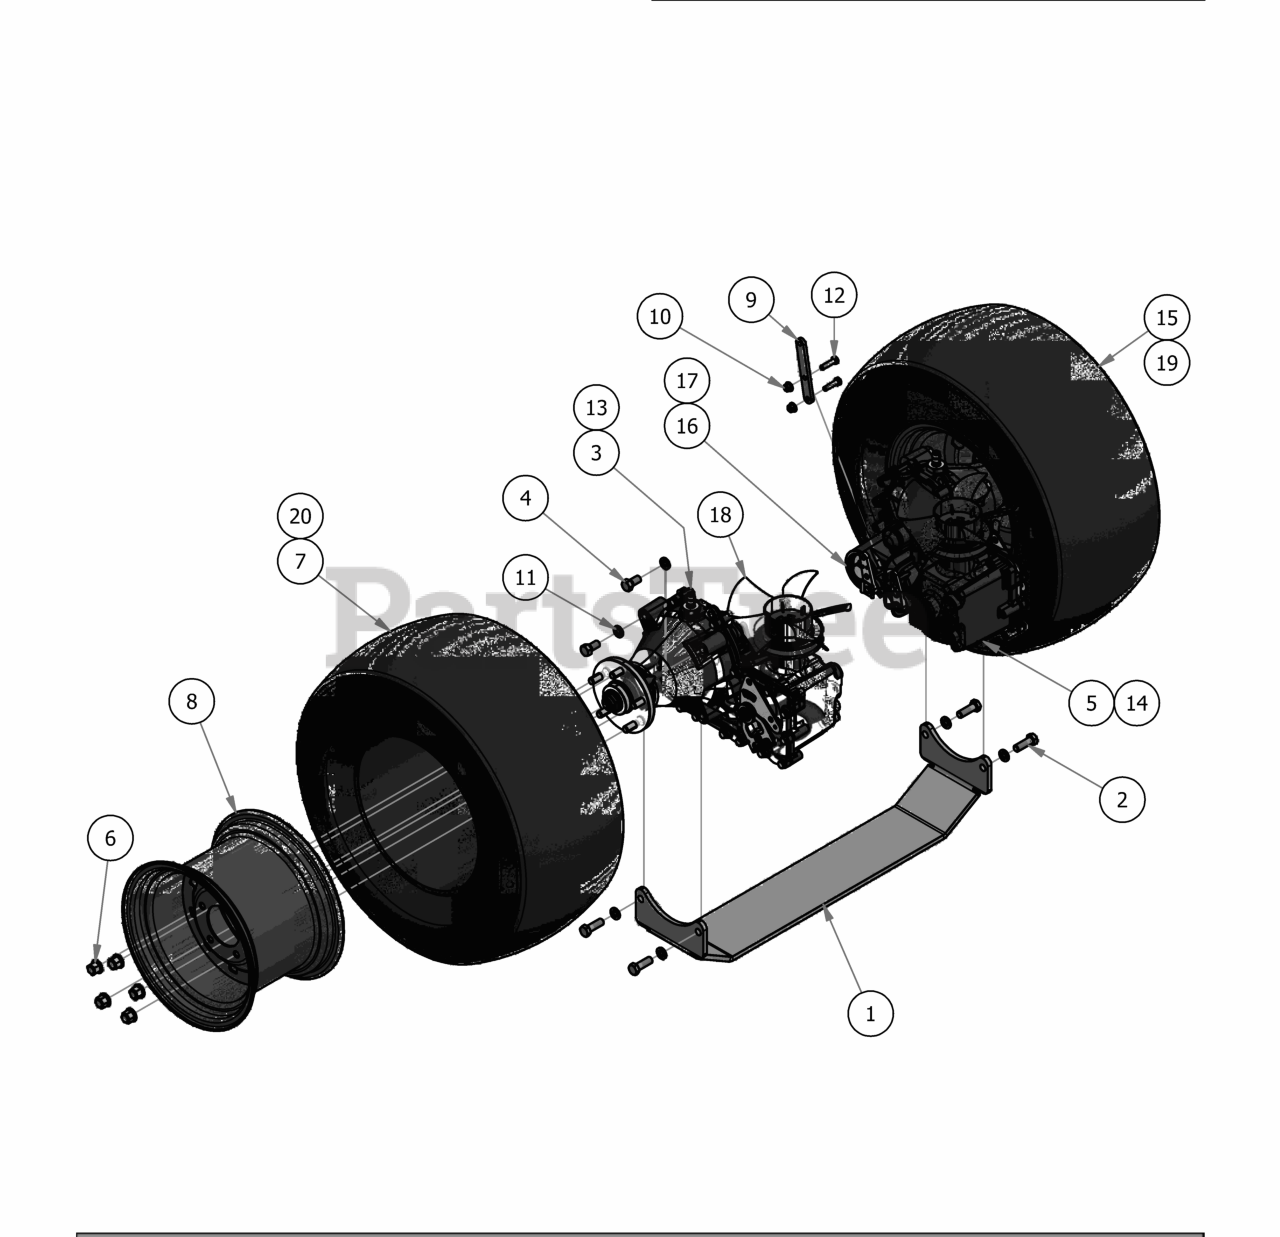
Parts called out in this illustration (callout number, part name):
1	Outlaw Transaxle Cross Brace
2	1/2" x 1 1/2" Hex Bolt
3	ZT - 5400 - Left
4	1/2" x 1" Hex Bolt
5	ZT - 5400 - Right
6	Acorn Lug Nut
7	24 x 12 - 12 Tire Pro Maxxis
8	12x12" Black Wheel For 2015 Outlaw
9	2015 Outlaw Brake Adapter (4400 Transaxles Only)
10	5/16" Flange Nut Zinc W/Serrations (4400 Transaxles Only)
11	1/2" Lock Washer
12	5/16 x 1 1/4 Hex Bolt (4400 Transales Only)
13	4400 Transaxle - Left (Base Outlaw)
14	4400 Transaxle - Right (Base Outlaw)
15	24 x 12.00 - 12 Tire and Black Wheel Assembly
16	Hydro Filter for Outlaw Extreme
17	4400 Hydro Filter for Outlaw
18	Fan/Pulley Kit for Oulaw
19	2018 24x12-12 Reaper Turf Tire and Black Wheel Assembly
20	2018 24x12-12 Reaper Turf Tire
